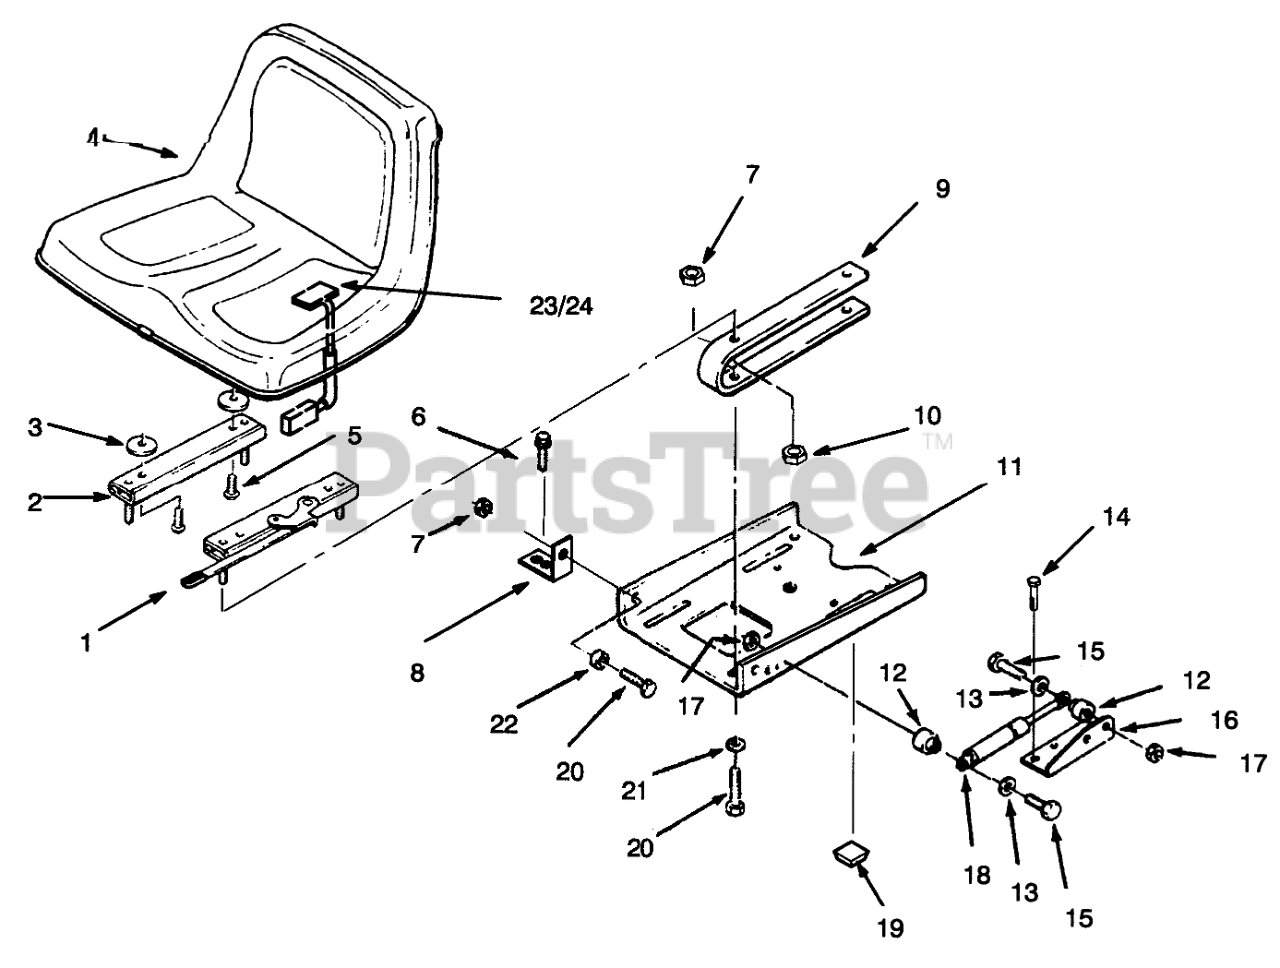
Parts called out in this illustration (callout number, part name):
1	Adjuster-Seat
2	ADJUSTER-R.H. SEAT
3	SPACER-NYLON
4	Seat
6	Bolt
7	NUT-LOCK, NI
8	BRACKET-PIVOT
9	Seat Spring
10	Nut
11	Plate-SeatPivot
12	SPACER
13	WASHER-FLAT
14	Bolt
15	SCREW-HH
16	BRACKET-CYLINDER R
17	NUT-LOCK, NI
18	GAS SPRING
19	BUMPER SJ5514 BLACK
20	SCREW-HH
21	WASHER-PLAIN
22	BUSHING
23	SWITCH-SEAT
24	SPEED CLIP
